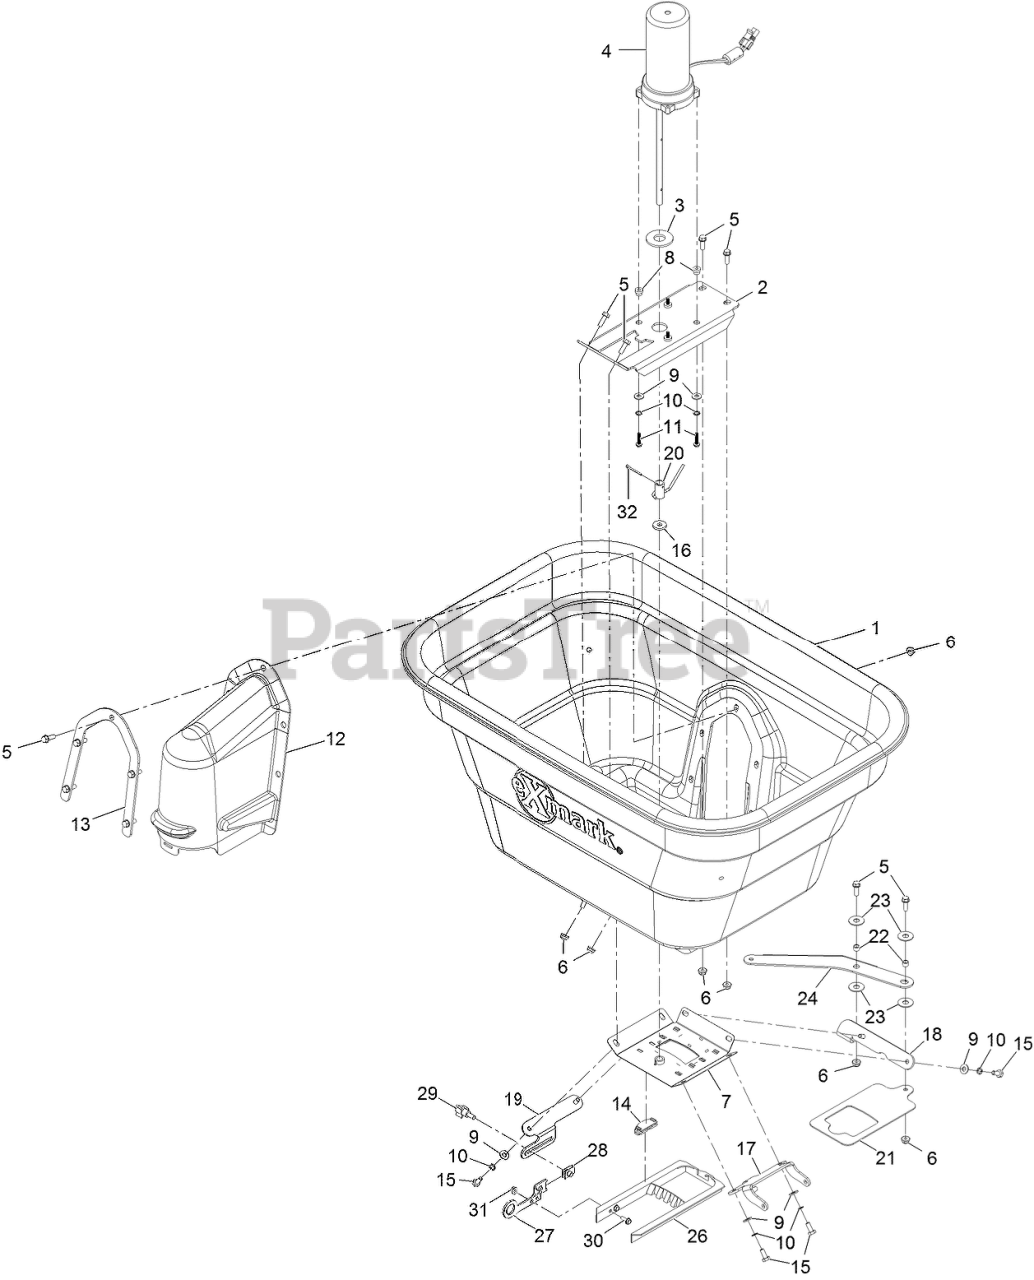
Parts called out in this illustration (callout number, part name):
1	HOPPER-SPREADER, 175 LB (
2	MOUNT-MOTOR
4	MOTOR-SPREADER
5	SCREW-HWH
7	GATE-BEARING
8	SPACER-FLANGED
9	WASHER-FLAT
10	WASHER-LOCK, INT
11	SCREW-SHWH
12	COVER-MOTOR
13	SUPPORT-COVER
14	GUIDE-RATE, GATE
15	SCREW-HH
16	WASHER-FELT
17	MOUNT-DEFLECTOR
18	MOUNT-GATE, PIVOT
19	MOUNT-GATE, PIVOT
20	WELD-AGITATOR
21	GATE-SPREADER, SEED
24	ARM-ENGAGEMENT
26	DIFFUSER
27	BRACKET-ACCUWAY, SLIDE
29	KNOB-STAR, THREE
31	NUT-LOCK, FLANGE
32	Pin-Cotter
